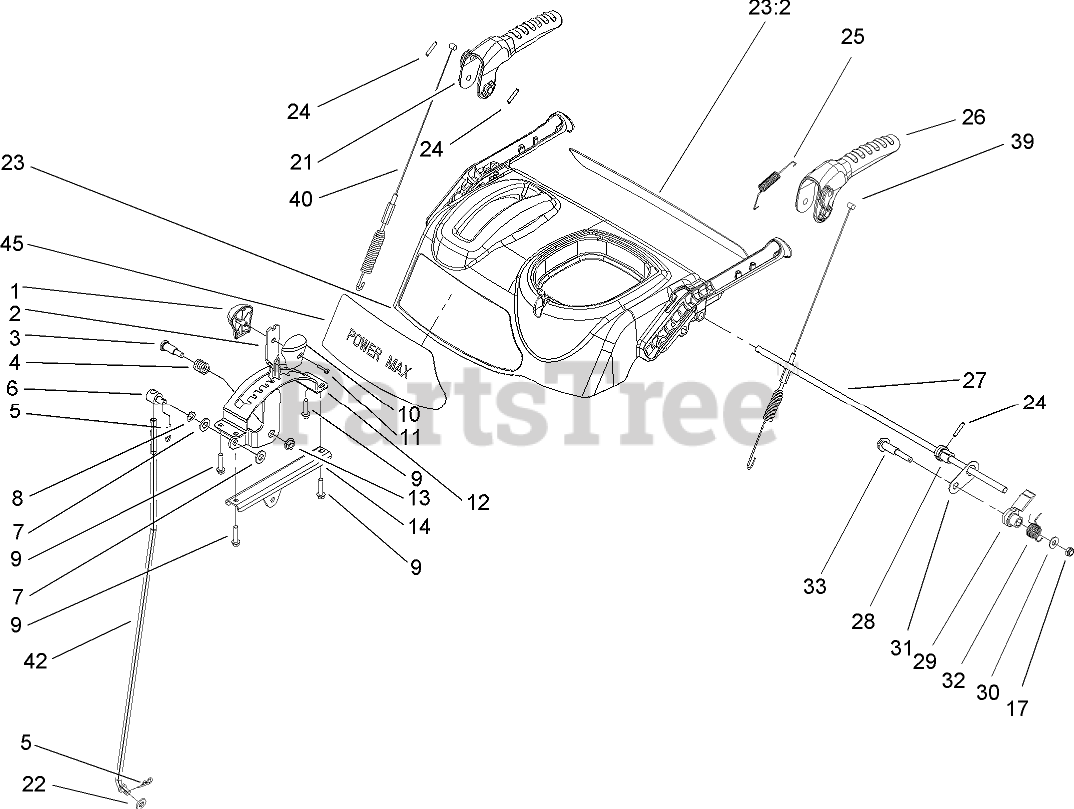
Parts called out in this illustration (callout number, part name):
1	KNOB-SHIFT, RH
2	SELECTOR-SPEED
3	SCREW-SHOULDER
4	SPRING-COMPRESSION
5	PIN-COTTER
6	TRUNNION
7	WASHER-FLAT
8	WASHER-SPRING
9	SCREW-PLASTITE
10	KNOB-SHIFT, LH
11	SCREW-PPH
12	GUIDE-SELECTOR, SPEED
13	NUT-HF
14	MOUNT-SELECTOR, SPEED
17	NUT-LOCK, NI
21	LEVER-AUGER
22	WASHER-FLAT
23	CONTROL PANEL ASM
23:2	DECAL-PANEL, BACK CONTROL
24	PIN-SPRING
25	SPRING-TENSION
26	LEVER-TRACTION
27	ROD-LOCKOUT
28	CAM-LOCKOUT
29	LATCH-LOCKOUT
30	WASHER-FLAT
31	LINK-LOCKOUT
32	SPRING-TORSION
33	SCREW-SHOULDER
39	CABLE-TRACTION
40	CABLE-AUGER
42	ROD-SHIFT
45	DECAL-CONTROL PANEL
